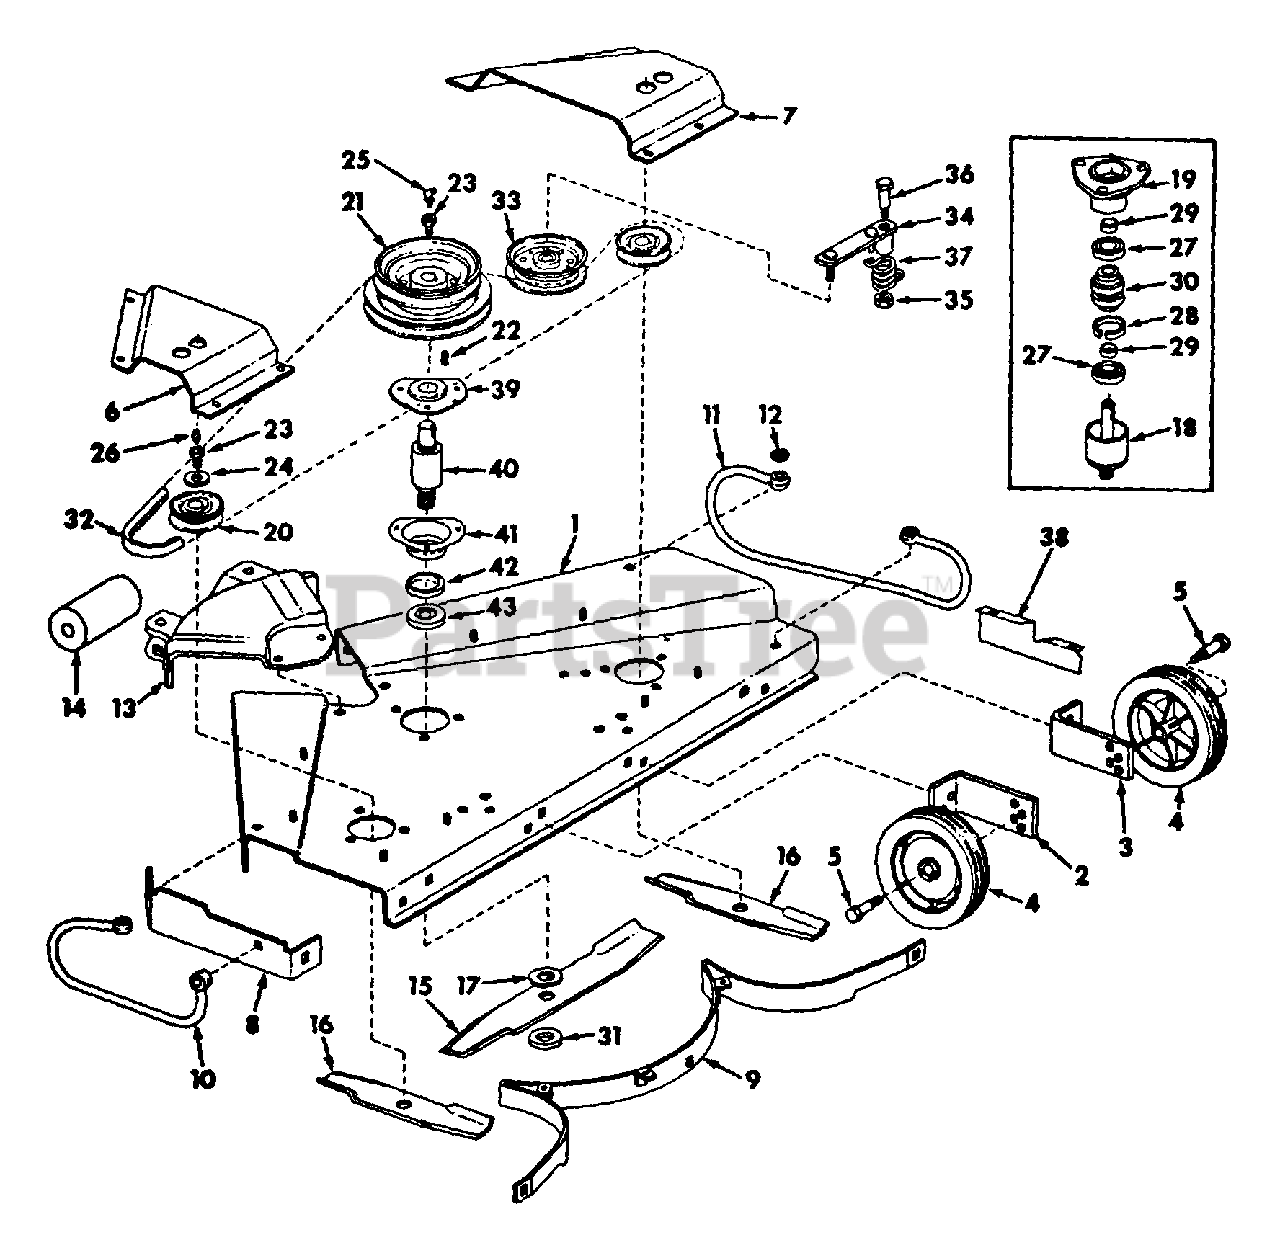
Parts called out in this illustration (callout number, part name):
1	HOUSING ASSY, ROTOR - 38 IN. BLADE
1	HOUSING ASSY, ROTOR - 42 IN. BLADE
2	ARM, GAUGE WHEEL LH
3	ARM GAUGE WHEEL RH
4	WHEEL, 7 IN. GAUGE
5	BOLT, SHOULDER
6	SHIELD, BELT LH
7	SHIELD BELT RH
8	SIDE, HOUSING LH - 38 IN. BLADE
8	SIDE, HOUSING LH - 42 IN. BLADE
9	SHROUD ASSY, BLADE - 38 IN. BLADE
9	SHROUD ASSY, BLADE - 42 IN. BLADE
10	RUNNER, MOWER LH
11	RUNNER, MOWER RH
12	WASHER, PLAIN 13/32 x 13/16 x .065 INCH
13	HOUSING, CENTER
14	ROLLER, FRONT
15	BLADE, CENTER - 38 IN. BLADE
15	BLADE, CENTER - 42 IN. BLADE
16	BLADE, OUTER - 38 IN. BLADE
16	BLADE, OUTER - 42 IN. BLADE
17	WASHER, BLADE FRICTION
18	SPINDLE ASSY, BLADE DRIVE DISC
19	HOUSING, SPINDLE
20	PULLEY, OUTER
21	PULLEY, CENTER
22	KEY, 1/4 x 3/4 x SQ. PARALLEL
23	BOLT, END
24	WASHER SPINDLE
25	FITTING, 3/8 DRIVE TYPE 45 DEG ANGLE LUB
26	FITTING, 5/16 DRIVE TYPE STR LUB
27	SEAL, SPINDLE OIL
28	SPACER, SPINDLE OUTER
29	SPACER, PULLEY
30	BEARING, SPINDLE
31	WASHER, 25/32 x 2 x 11 GA
32	BELT, SPINDLE DRIVE - 38 IN. BLADE
32	BELT, SPINDLE DRIVE - 42 IN. BLADE
33	PULLEY, FLAT IDLER
34	ARM ASSY, IDLER
35	NUT, CENTER LOCK
36	BOLT, IDLER ARM PIVOT
37	SPRING, TORSION
38	MULCHER - 38 IN. BLADE
38	MULCHER - 42 IN. BLADE
39	CAP, SPINDLE HOUSING
40	BEARING, BALL FAN & PUMP TYPE
41	HOUSING, SPINDLE
42	CUP, SPINDLE
43	SPACER, BLADE
18684-R1	BOLT, 3/8 x 1-1/4 C-Z SQ-NK CRG
18684-R1	BOLT, 3/8 x - 4 C-Z SQ-NK CRG
18685-R1	BOLT, 3/8 x 1-1/2 C-Z SQ-NK CRG
22476-R1	BOLT, 3/8 x 1-1/8 ZNP SQ-NK CRG
